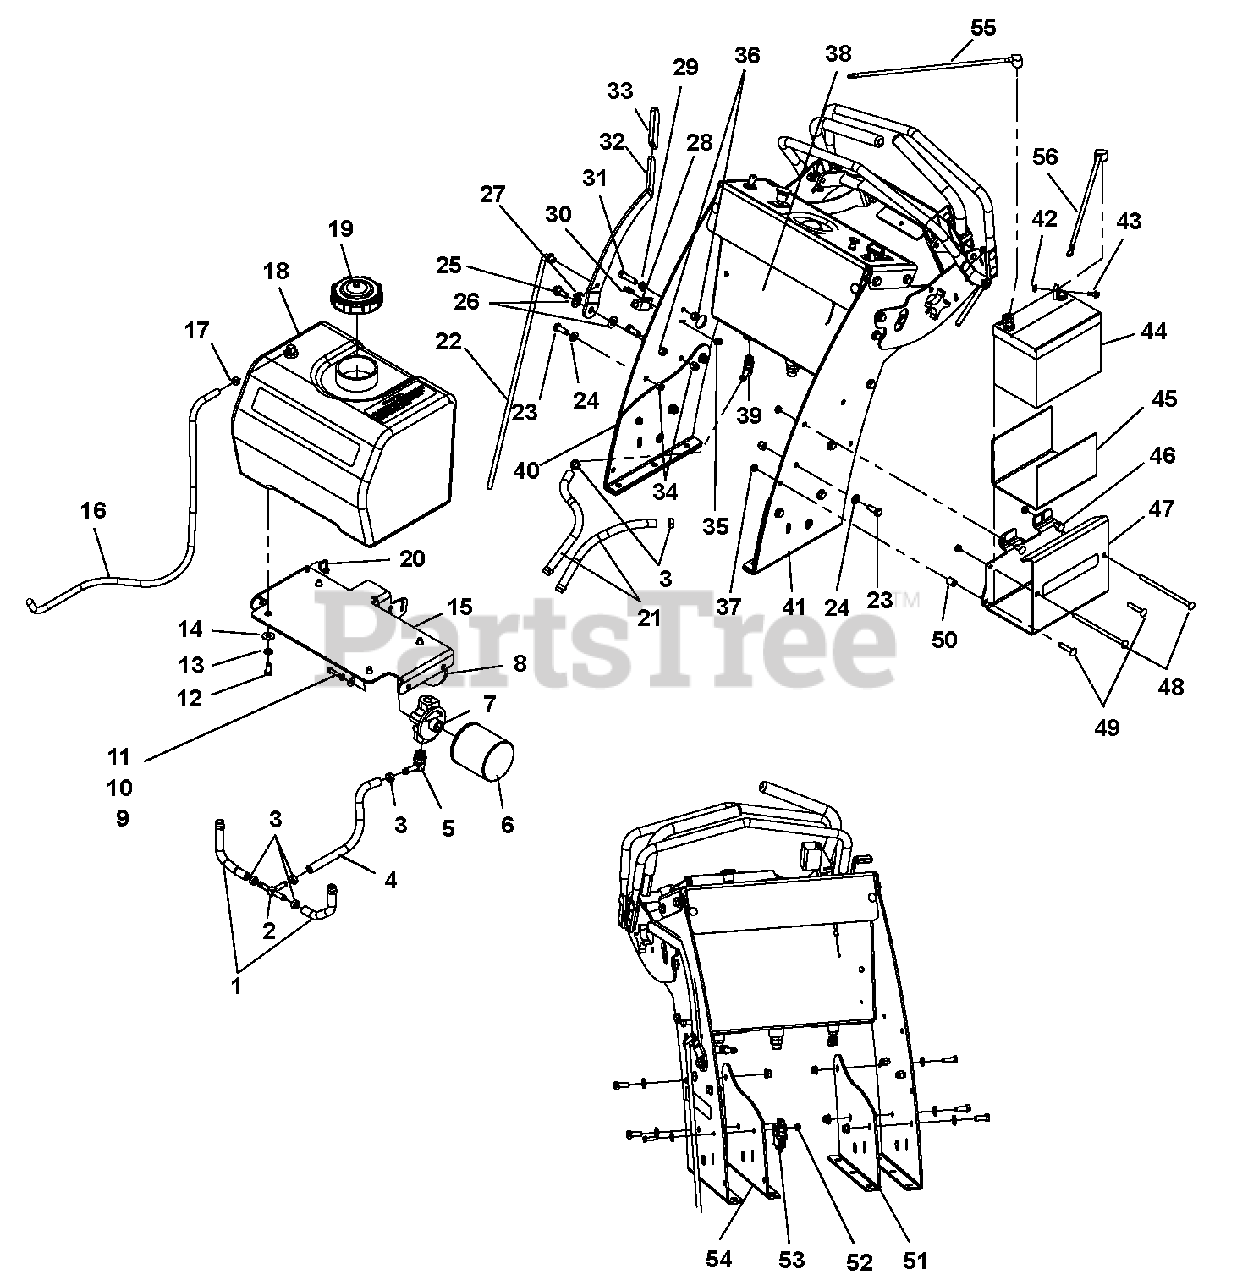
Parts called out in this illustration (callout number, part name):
1	Hose, Hydraulic .375 x 6.00
2	Fitting, TUN .375 Hose
3	Clamp, Hose - 1/2" Pinch
4	Hose, Hydraulic .375 x 10.5
5	Fitting, 90 Deg. Barb-OR
6	Filter, Oil
7	Head, Oil Filter
8	Guard, Hydraulic Filter
9	Washer, .250 Regular Flat
10	Washer, .250 Medium Spring Lock
11	Bolt, .25-20 x 1.00 Hex Grade 5
12	Bolt, .38-16 x .75 Hex Grade 5
13	Washer, .375 Medium Spring Lock
14	Washer, .375 Regular Flat
15	Bracket, Fuel Tank
16	Hose, Fuel .25 x 15.00
17	Clamp, Fuel Line
18	Fuel Tank, Rev B
19	Cap, Fuel
20	Cable Tie, .15 x 8.50
21	Hose, Hyd. .375 x 11.5
22	Rod, Drive Control
23	Bolt, .38-16 x 1.00 Hex Grade 5
24	Washer, .406 x .813 x .065 Flat
25	Bolt, .50 x 1.06 x .375-16 Grade 5
26	Washer, .510 x 1.00 x .068 Nylon
27	Ring, Rue .375 x .054 x 1.254
28	Switch- Double Pole N.O./N.O.
29	Locknut, .375-16 WHIZ
30	Screw, 10-24 x .625 Phillips Head
31	Bolt .38-16 x 1.50 Hex Grade 5
32	Lever, Hand Brake
33	Grip, PVC .250 x 1.00 x 3.63
34	Locknut, .375-16 Nyloc
35	Locknut, 10-24 Nyloc
36	Locknut, .375-16 Center
37	Locknut, .3125-18 Nyloc
38	Weldment, Hydraulic Tank
39	Fitting, 90 .5625 MOR x .375 Hose
40	Weldment, RH Upright Tower 18"
41	Weldment, LH Upright Tower 18"
42	Locknut, .25-20 (988141, 142)
43	Bolt, .25-20 x .625 (988141, 142)
44	Battery, 12V-U1-CCA270 (988141, 142)
45	Strip, Battery Insulator (988141, 142)
46	Bolt, Round Head Square Neck .31-18 x .75 Grade 5 (988141, 142)
47	Tray, Battery (988141, 142)
48	Bolt, .3125-18 x 6.00 Grade 2 (988141, 142)
49	Bolt, .31-18 x 1.75 Round Head Square Neck Grade 5 (988141, 142)
50	Bushing, .364 x .540 x .700 (988141, 142)
51	Plate, Double LH Upright
52	Locknut, .25-20 Nyloc (988140)
53	Module, Electronic (988140)
54	Plate, Double RH Upright
55	Cable, Battery Ground 25" (988141, 142)
56	Cable, Battery Positive 25" (988141, 142)
